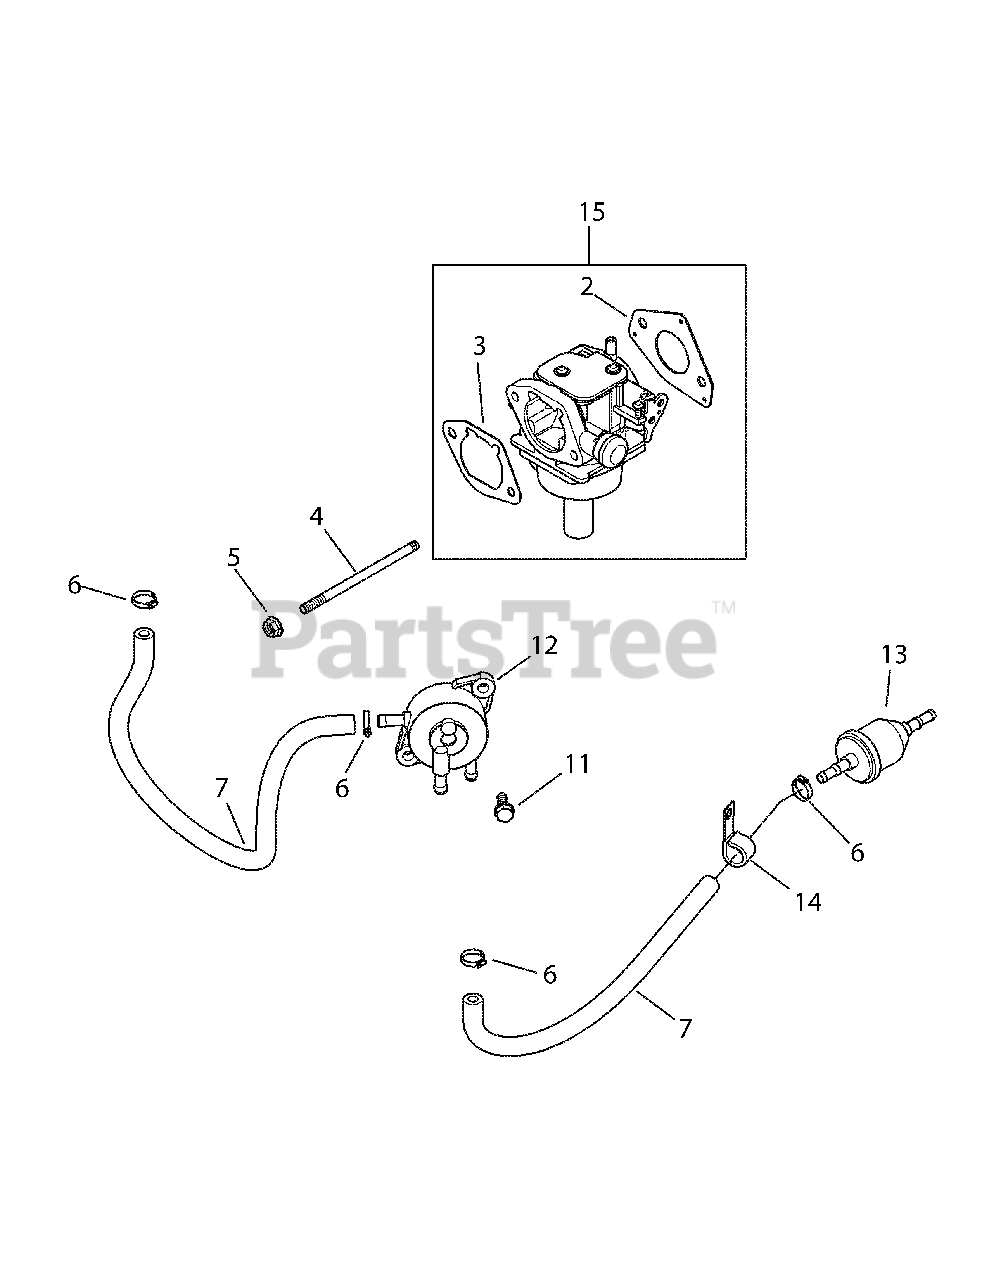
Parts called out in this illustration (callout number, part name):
2	Carburetor Gasket
3	Air Cleaner Base Gasket
4	Stud, M6 X 1.0 X 106
5	Flg. Nut, M6 X 1.0
6	Hose Clamp, 1/2
7	Fuel Line
11	Tap Screw, M6 X 1.7 X 18
15	Carburetor Kit, 19mm (Inc. 2 & 3)
